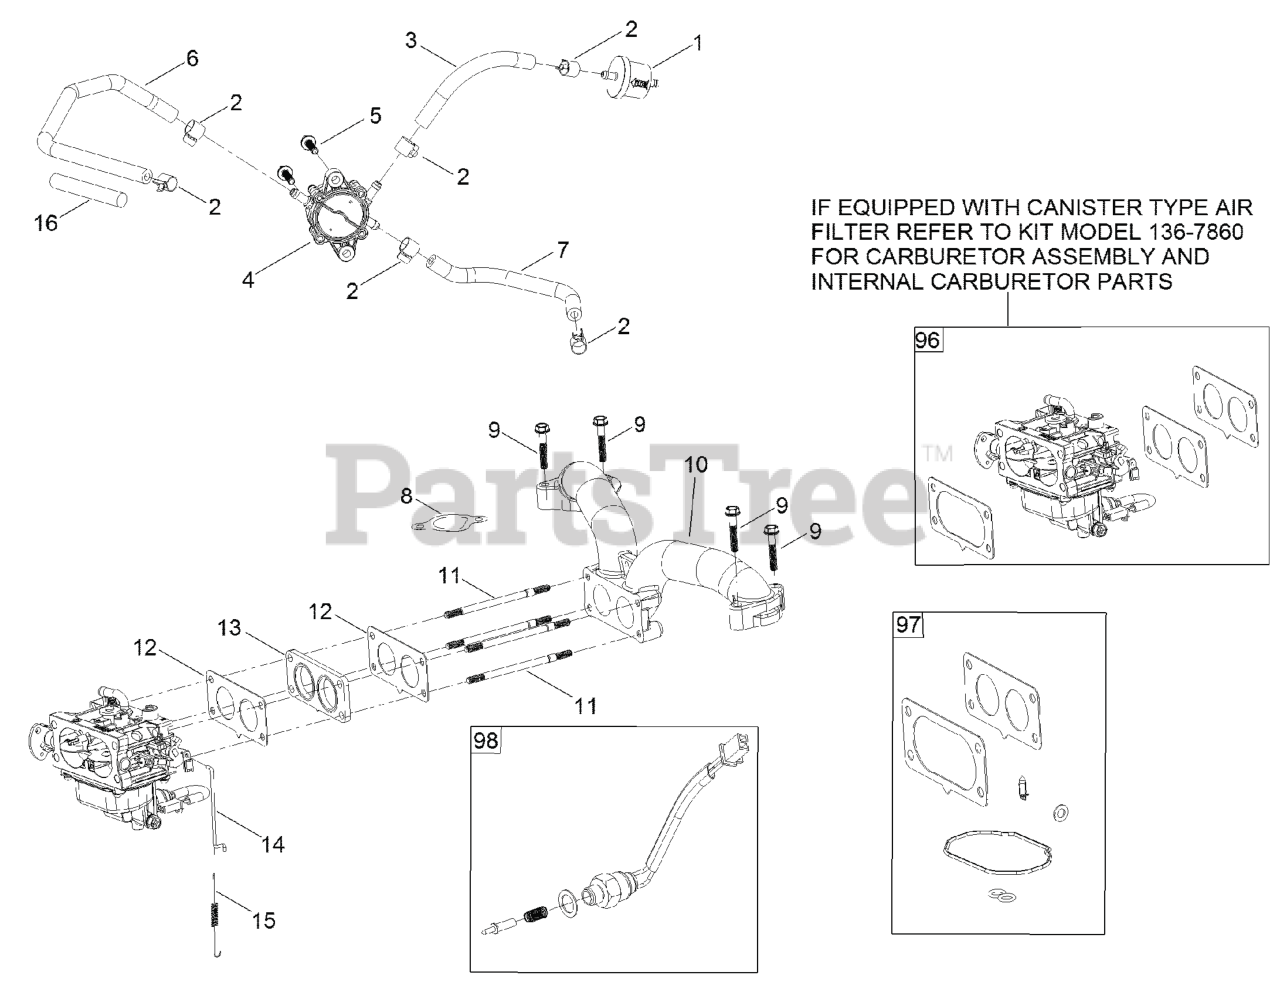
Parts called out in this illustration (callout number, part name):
1	FILTER-FUEL
2	CLAMP-FUEL LINE
3	LINE-FUEL
4	PUMP-FUEL
5	SCREW-HHF
6	HOSE-FUEL
7	HOSE-FUEL
8	GASKET-INTAKE
9	SCREW-HHF
10	MANIFOLD-INTAKE
12	GASKET-CARBURETOR
13	INSULATOR-CARBURETOR
14	LINKAGE-THROTTLE
15	SPRING-RETURN, THROTTLE
16	SLEEVE-FUEL LINE PROTECTO
96	CARBURETOR REPLACEMENT KI
97	CARBURETOR REPAIR KIT
98	SOLENOID KIT
